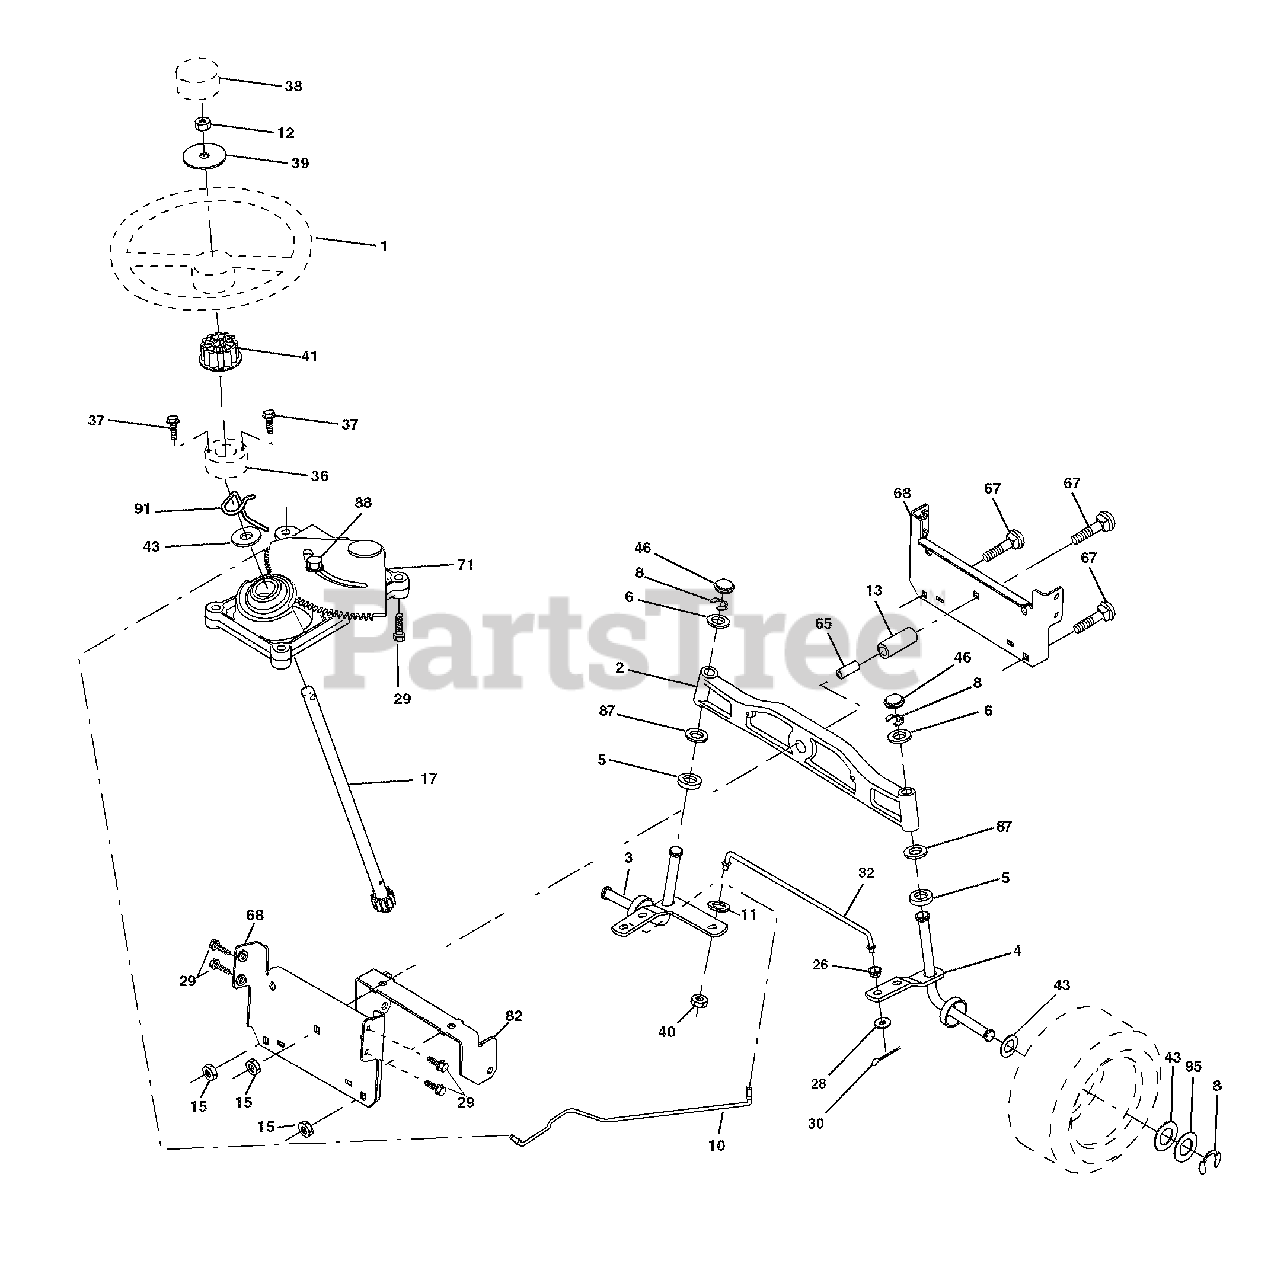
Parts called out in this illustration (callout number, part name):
1	Wheel Steering
2	Axle Asm Cast Iron LT
3	Spindle Asm LH
4	Spindle Asm RH
5	Bearing Race Thrust Harden
6	Washer 25/32 x 1-5/8 x 16 Ga.
8	Ring Clip #T5304-75
11	Washer Lock Hvy Hlcl Spr 3/8
12	Nut Hex Jam Toplock 1/2-20 unf
13	Spacer Brg Axle Front
15	Nut Hex Flange Lock
17	Shaft Asm Steering
26	Bushing Link Drag
28	Washer 13/32 x 7/8 x 16 Ga.
29	Screw 3/8-16 x .75
30	Pin Cotter 1/8 x 3/4
36	Bushing Strg
38	Insert Cap Strg Wh
39	Washer 9/16 ID x 2-3/8 OD x 12 Ga.
40	Crownlock Nut
41	Adapter Wheel
43	Washer 25/32 x 1 1/4 x 16 Ga.
46	Cap Spindle Fr Top Blk
65	Spacer Brace Axle
67	Bolt RDHD SQNK 3/8-16 x 2 1/4
68	Axle, Brace
71	Steering Asm
82	Bracket Susp Chassis Front
87	Washer Flat .781 x 1-1/2 x .14
88	Bolt Shoulder 7/16-20 unc
91	Clip Steering
95	Washer Harden .739 x 1.637 x 060
